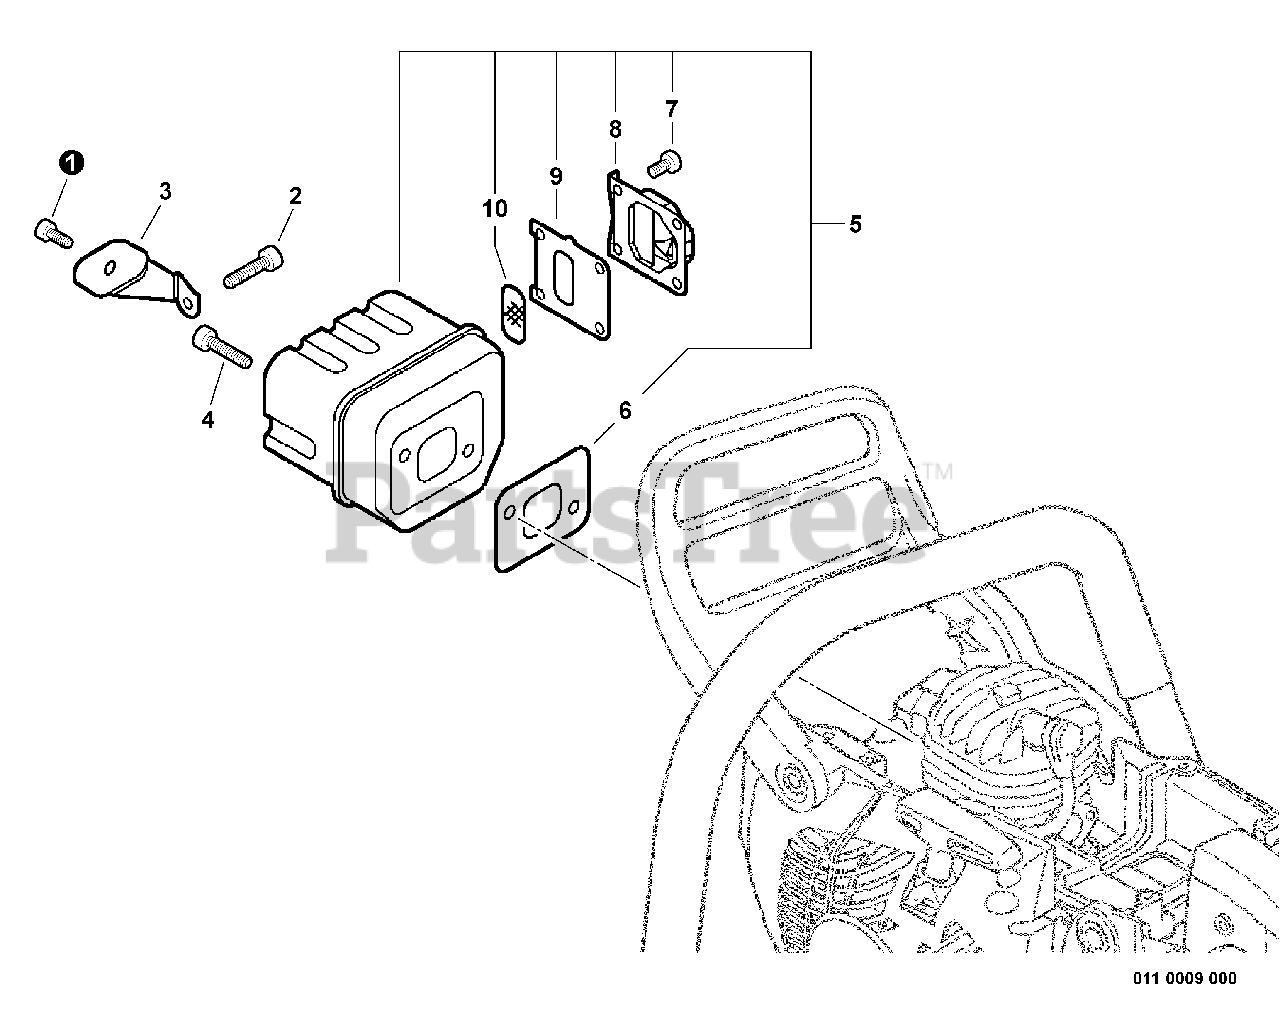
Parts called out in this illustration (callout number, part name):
1	BOLT 6×8
2	SCREW 6×14
3	BRACKET, MUFFLER
4	BOLT 5×16
5	MUFFLER ASSY
6	GASKET, MUFFLER
7	SCREW 4×10
8	GUIDE, EXHAUST
9	GASKET, EXHAUST
10	SCREEN, SPARK ARRESTER
